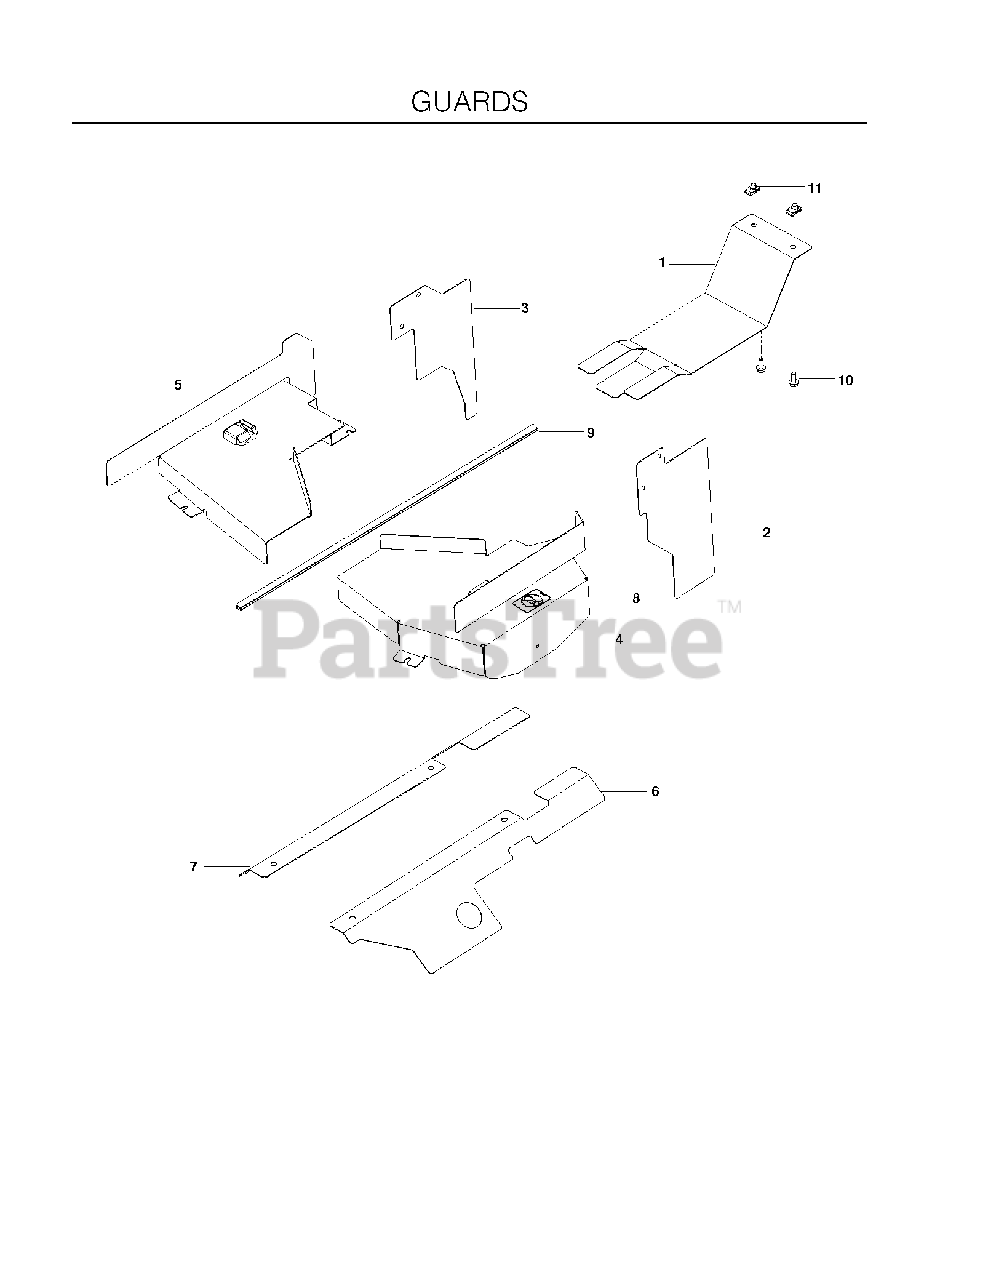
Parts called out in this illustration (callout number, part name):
8	DECAL, NO STEP
9	FLEX TRIM, BLACK
10	HHFS 5/16-18 X 3/4
11	U-CLIP 5/16-18 NUT RETAINER
